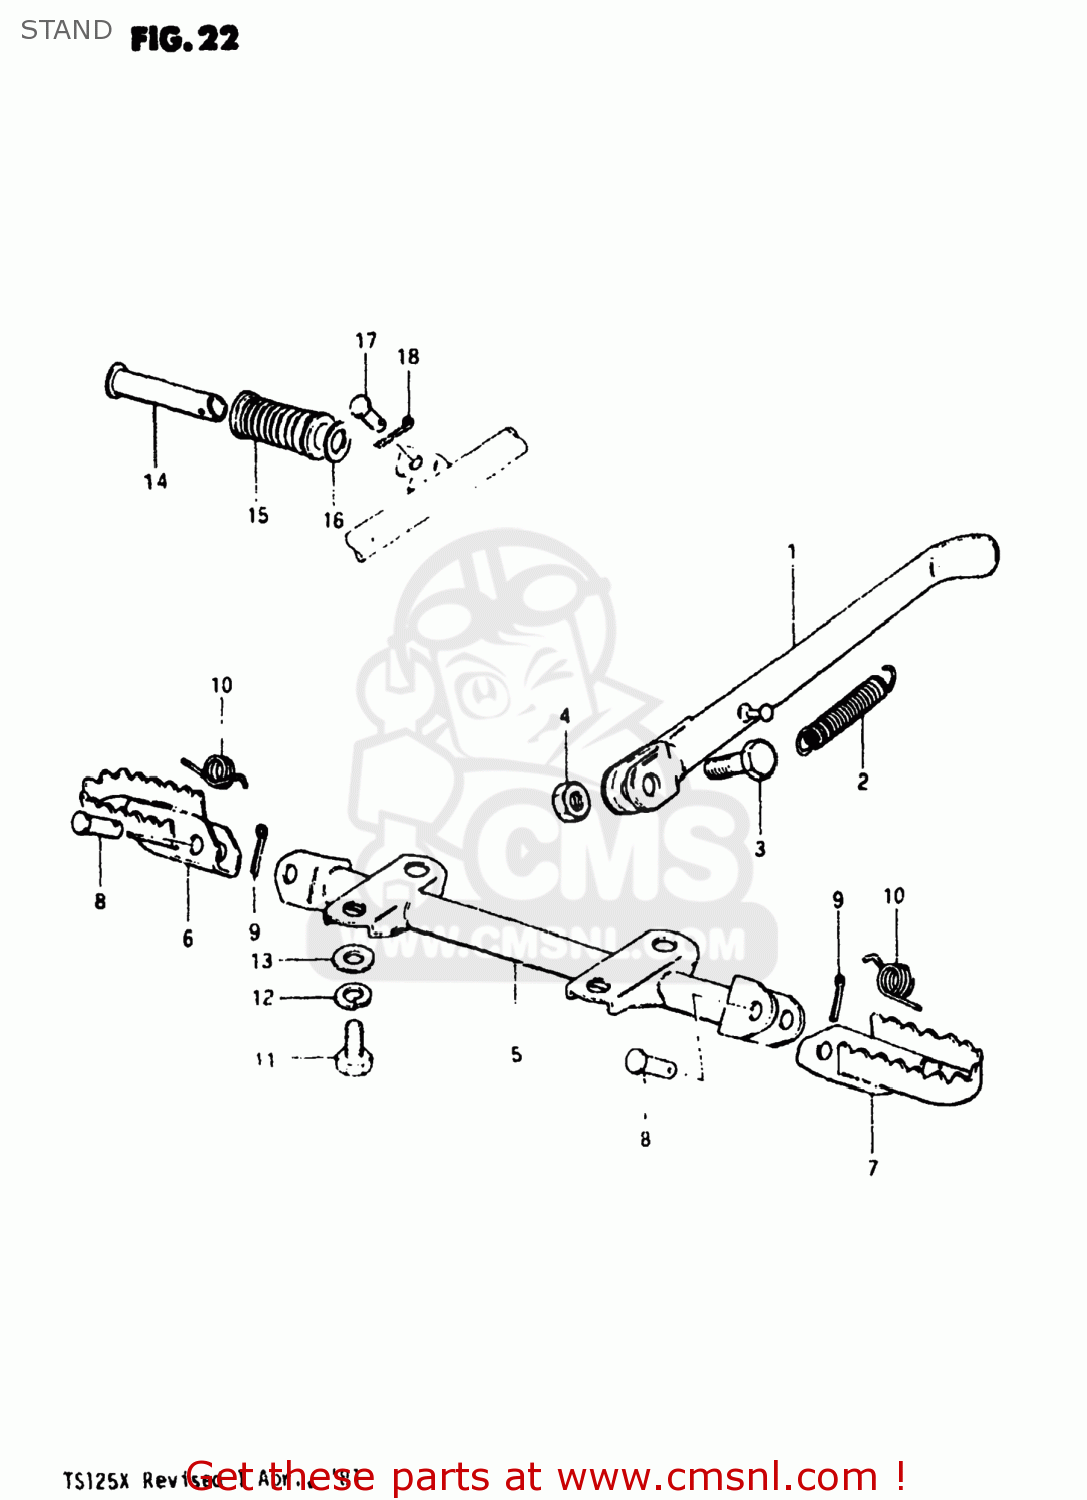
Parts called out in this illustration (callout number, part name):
1	STAND,PROP
2	SPRING
3	BOLT(10X30)
4	NUT
5	BAR,FR FOOTREST
6	FOOTREST,FRONT
7	FOOTREST
8	PIN
9	PIN 20X20
10	SPRING
11	BOLT
12	LOCK WASHER
13	WASHER
14	BAR,FOOTREST RUBBER
15	RUBBER,PILLION FOOTREST
16	WASHER (19.5X32X2)
17	PIN
18	PIN 20X20
